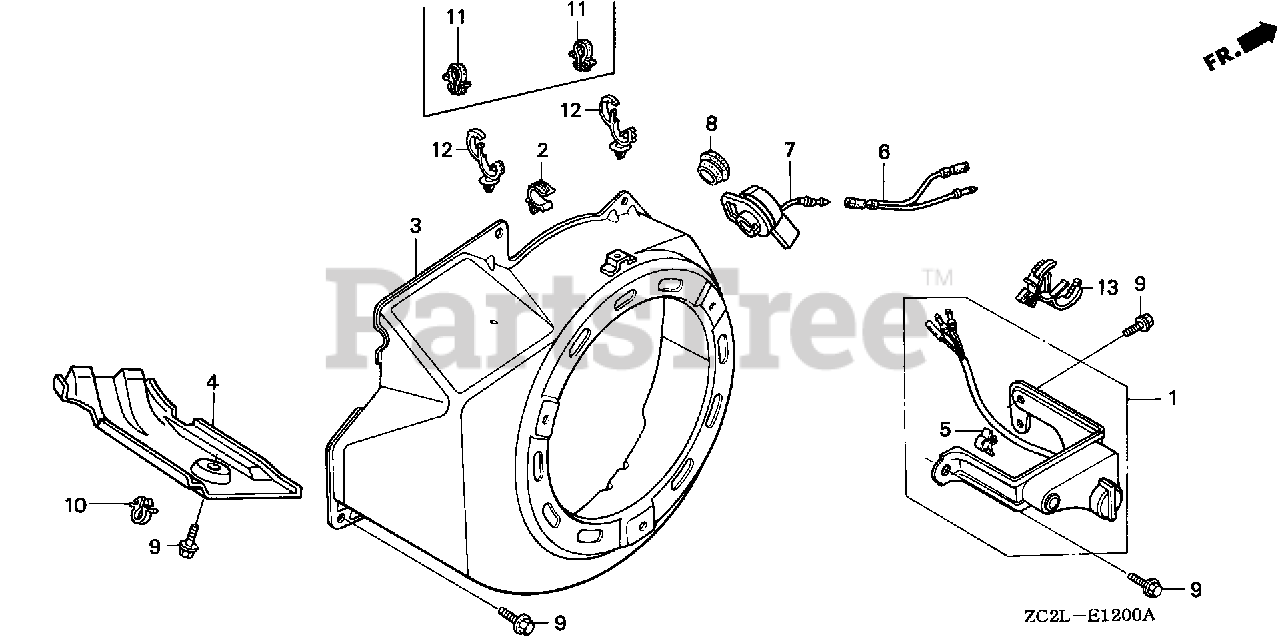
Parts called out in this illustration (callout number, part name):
3	COVER, FAN *NH1* (BLACK)
8	GROMMET, DRAIN HOLE
9	BOLT, FLANGE (6X12) (CT200)
10	CLIP, WIRE HARNESS (6MM) (WHITE)
12	CLIP (20MM)
